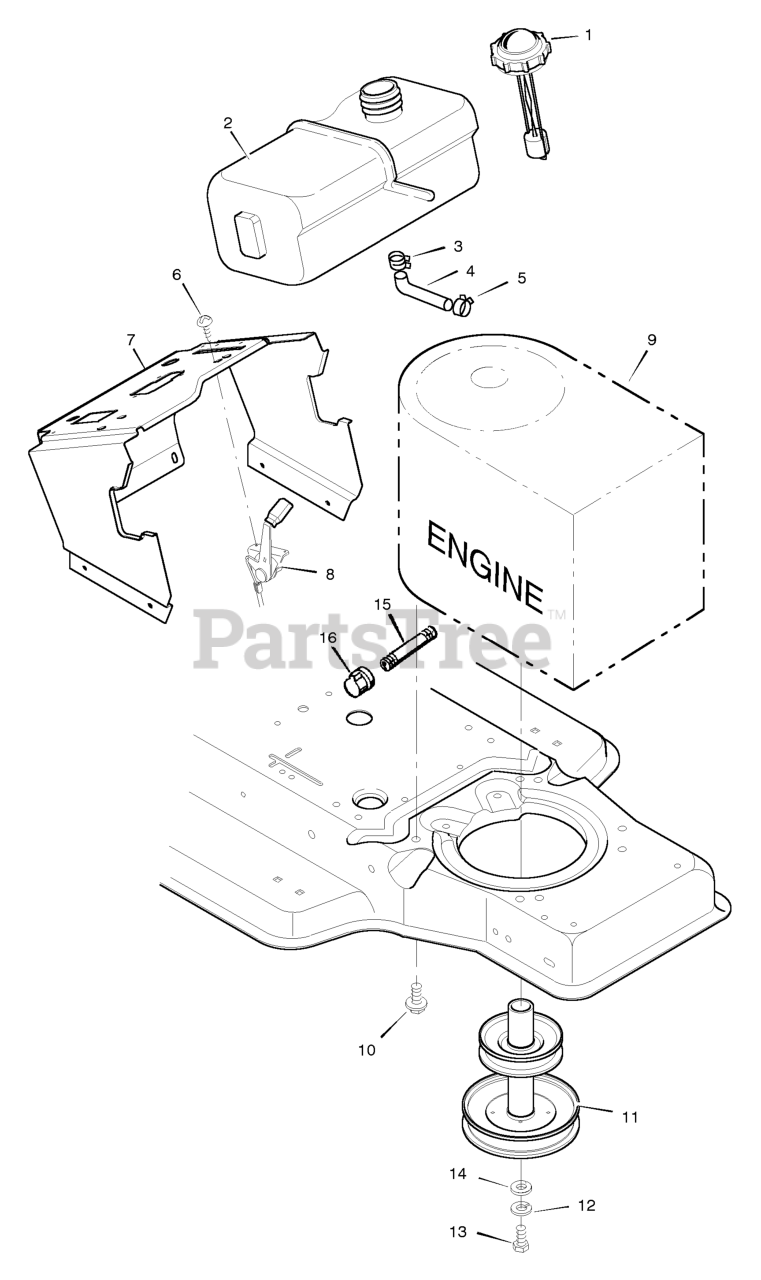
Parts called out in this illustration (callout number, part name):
1	Fuel Cap
2	Fuel Tank
3	Hose Clamp
4	Fuel Line
5	Hose Clamp
7	Support, Dash
8	Throttle Control
9	Engine *
10	Bolt, Engine Mount
11	Stack Pulley Assembly
12	Lockwasher
13	Bolt, Hex
15	Pipe, Oil Drain
16	Cap, Oil Drain
